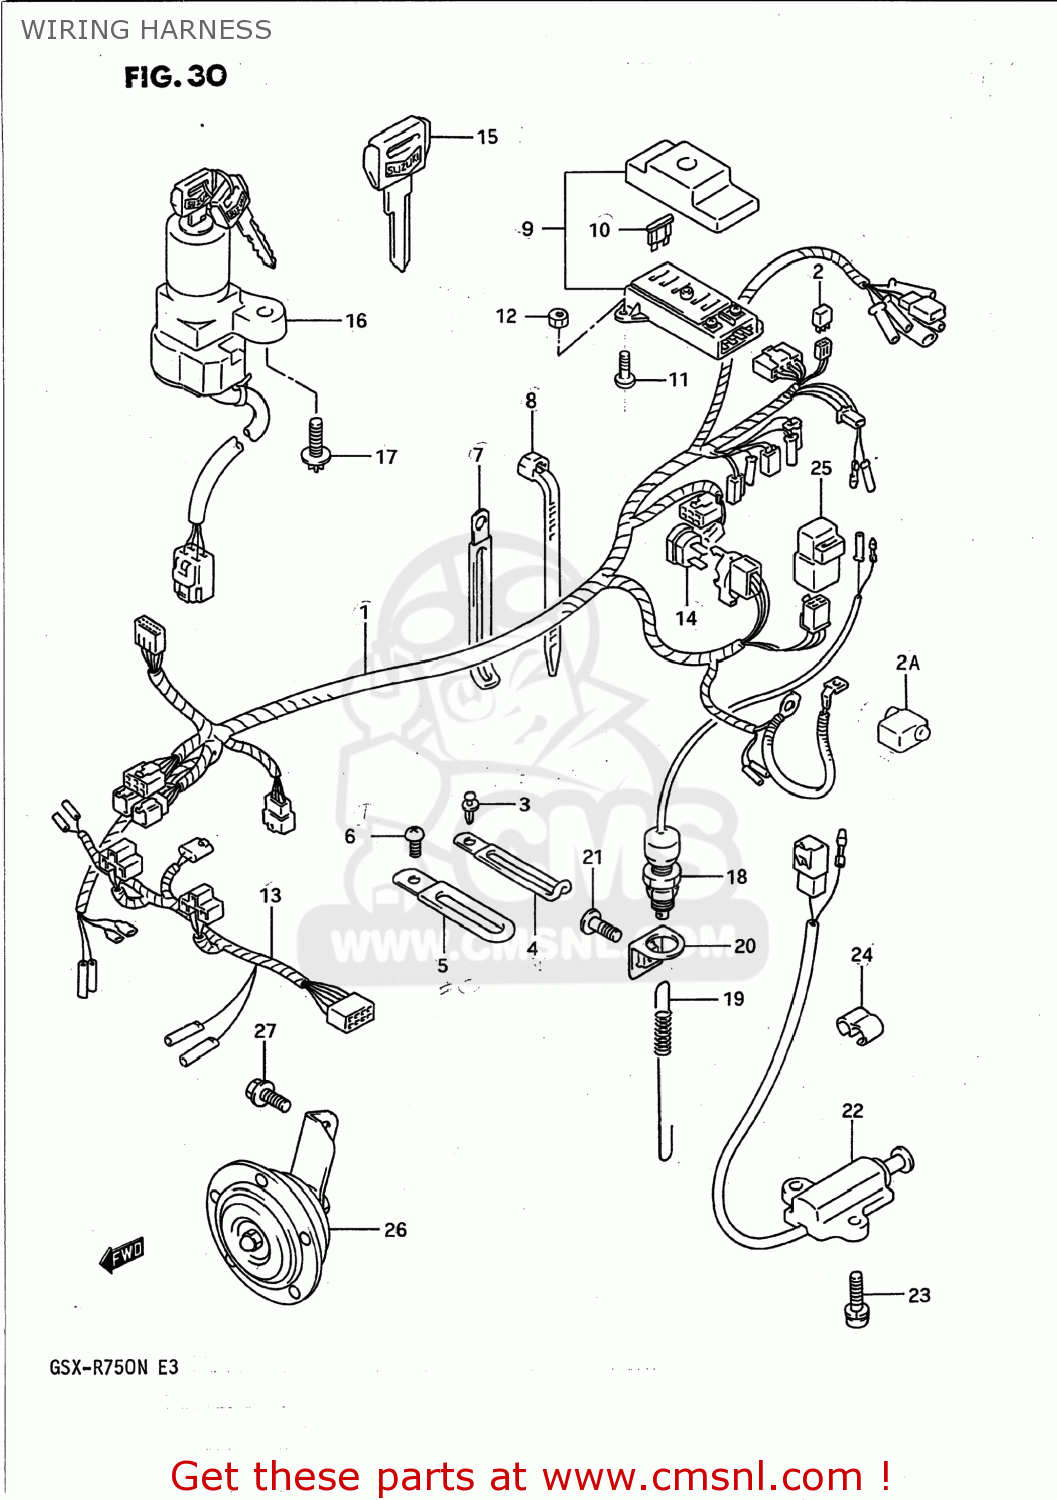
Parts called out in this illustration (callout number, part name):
1	HARNESS,WIRING
2	DIODE(STANLEY DE8804)
2A	CAP,BATTERY PLUS
3	CLIP
4	CLAMP
5	CLAMP
6	SCREW
7	CLAMP
8	CLAMP(L:95)
9	BOX ASSY,FUSE
10	FUSE(10A)
11	SCREW (6X15)
12	NUT 6MM
13	WIRE
14	BREAKER ASSY,CIRCUT
15	KEY,BLANK
16	LOCK ASSEMBLY,STEERING
17	SCREW(6X18)
18	SWITCH ASSY,STOP LAMP
19	SPRING
20	BRACKET,STOP LAMP SWITCH
21	SCREW(6X12)
22	SWITCH ASSEMBLY,SIDE STAND
23	SCREW
24	CLIP
25	RELAY ASSEMBLY
26	HORN ASSEMBLY
27	BOLT
